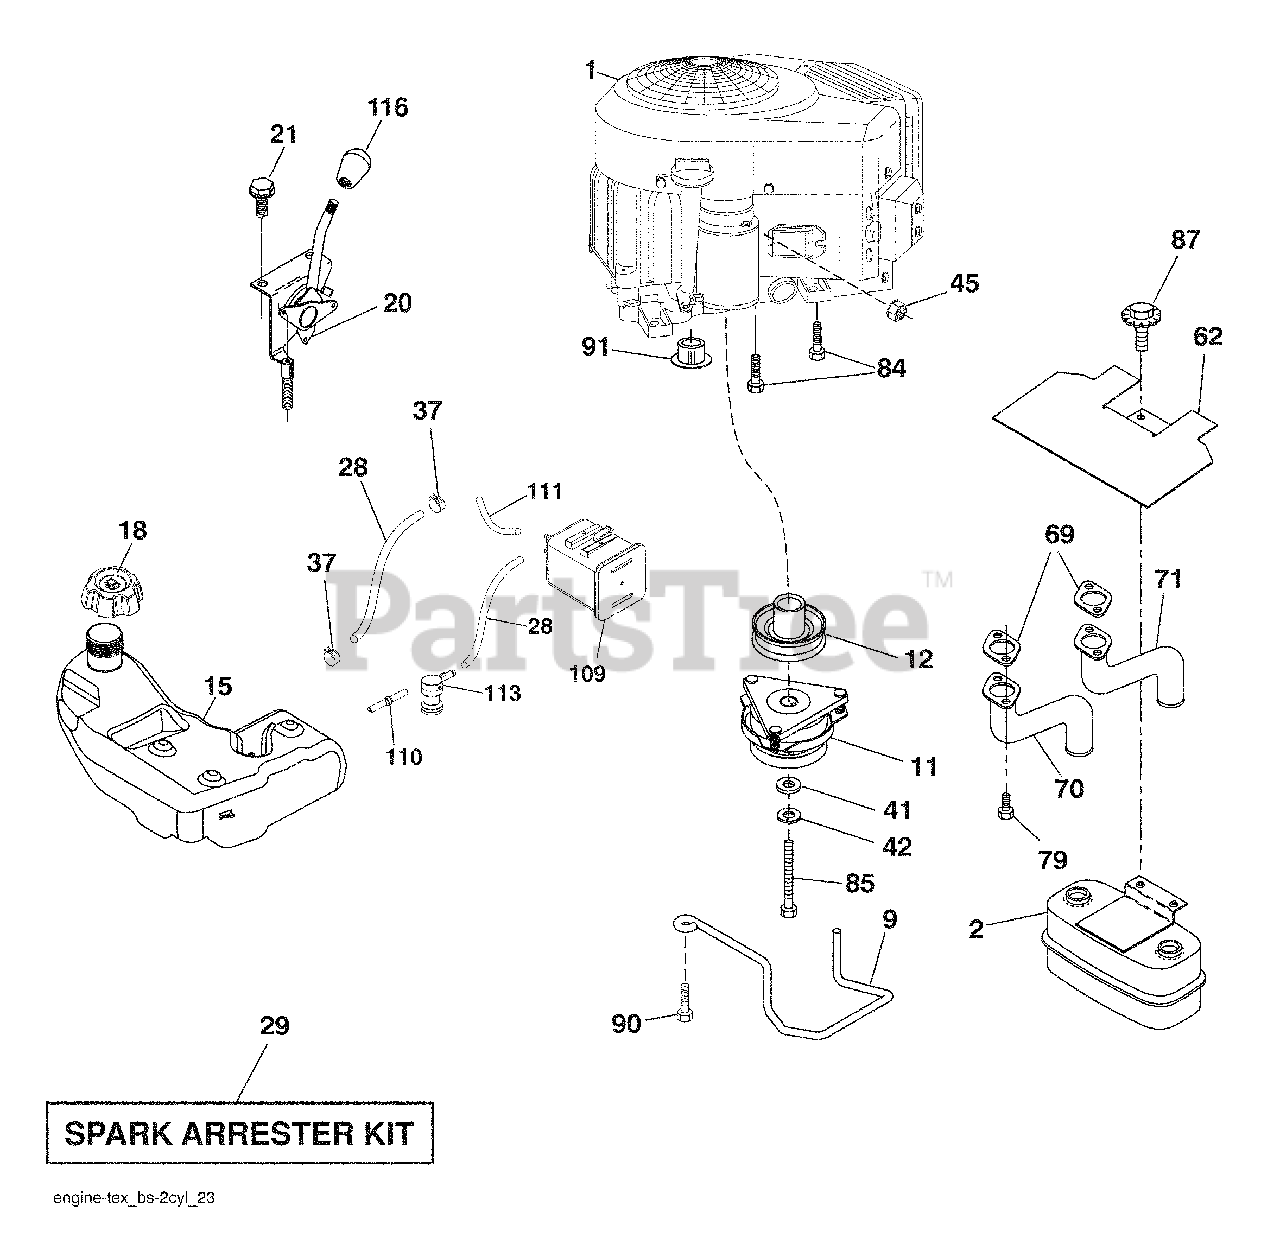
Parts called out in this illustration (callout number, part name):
9	Keeper Belt Engine
11	Clutch Electric
12	Pulley Engine
18	Cap Asm
20	Control Throttle/Choke
21	Screw #10 x 0.750
28	Fuel Line
29	Spark Arrester Kit
37	Clamp Hose
41	Washer 1-1/2 OD x 15/32 ID x .250
42	Washer Lock 7/16
45	Nut Keps Hex 1/4-20 unc
62	Shield Heat Muffler
70	Tube Exhaust LH
71	Tube Exhaust RH
79	Screw Socket Head 5/16-18 x 1
84	Screw 3/8-16 x 1-1/4
85	Bolt Hex 7/16-20 x 4 x Gr. 5-1.5 Thr
87	Bolt 5/16-18 unc x 3/4 w/Sems
90	Screw 3/8-16 x 1
109	Canister Carbon Filter Asm.
110	Valve Anti-Slosh
111	Purge Line
113	Valve Slant Cartrdg
116	Knob Soft Touch
